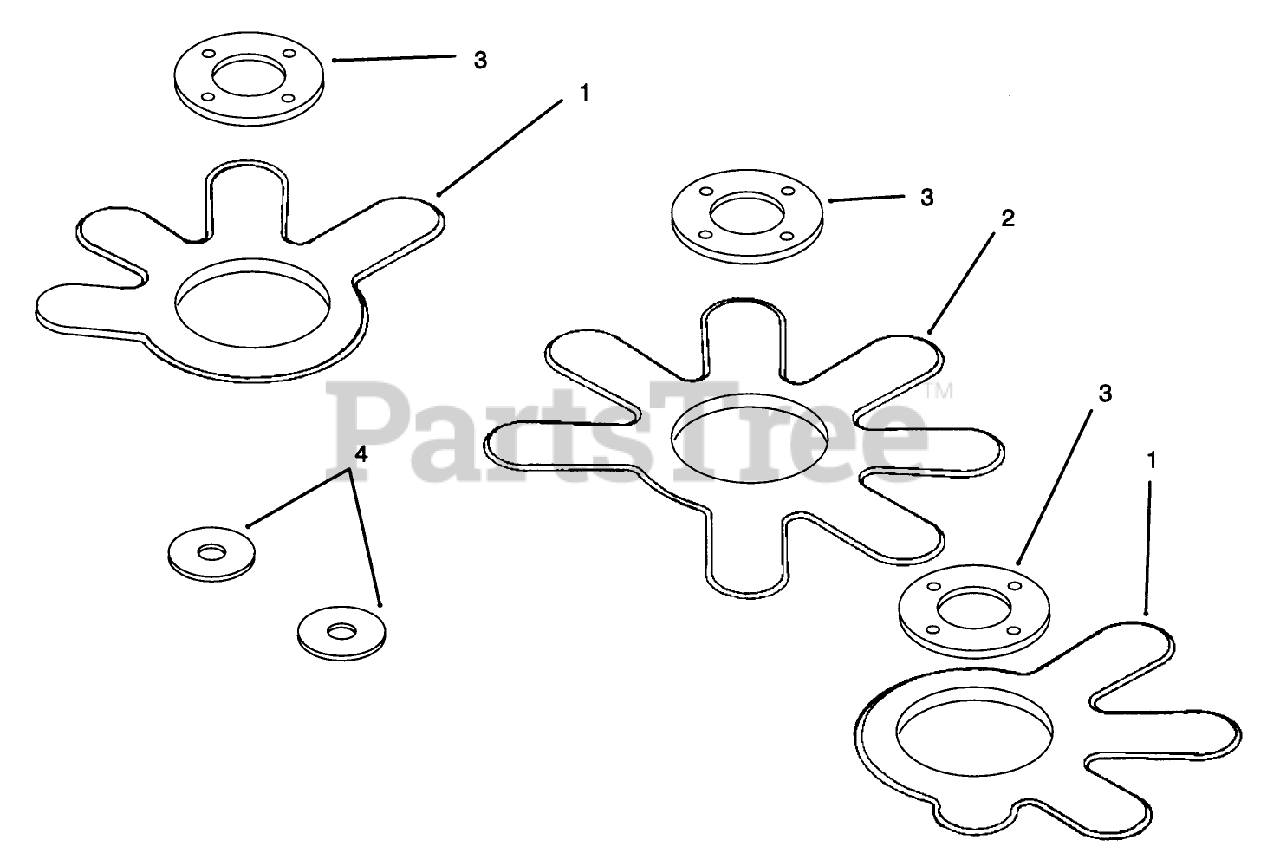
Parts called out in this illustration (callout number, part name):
1	PLATE-DECK
2	PLATE-DECK
3	PLATE-SPINDLE
4	WASHER-SPACER
